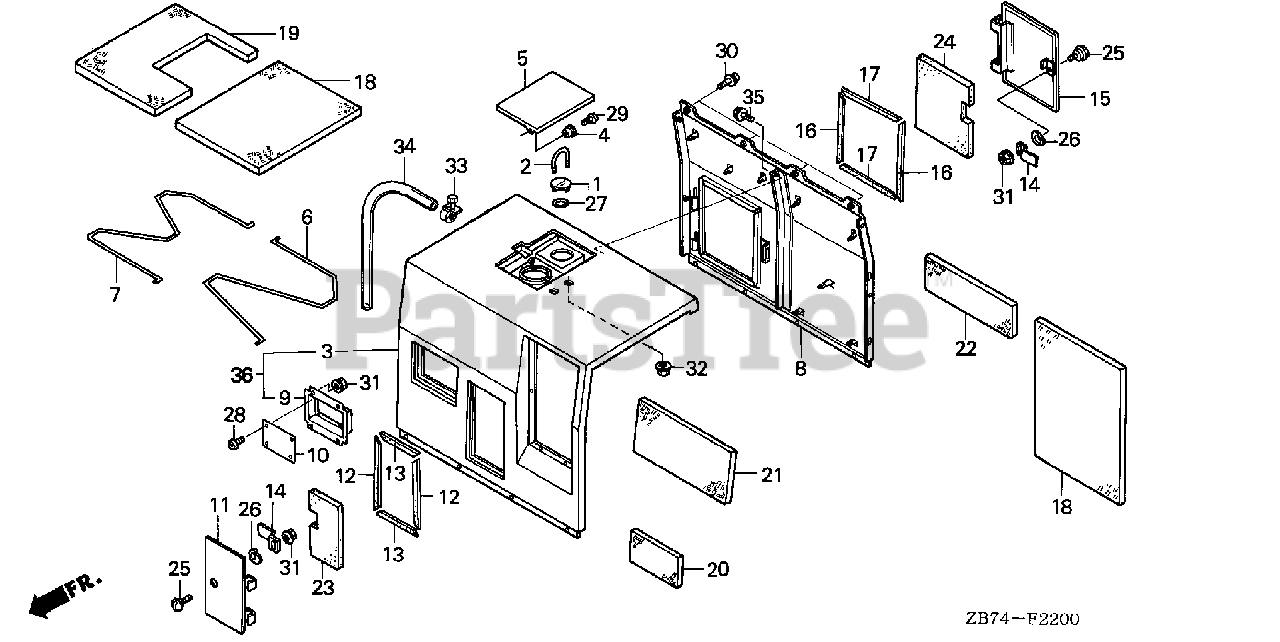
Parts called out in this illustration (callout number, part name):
1	CAP, FUEL METER
2	HOOK, HANGER
4	BUSH, FUEL CAP COVER
5	COVER, FUEL CAP *R280* (POWER RED)
6	WIRE, R. INSULATOR HOLDER
7	WIRE, L. INSULATOR HOLDER
8	PANEL, RR. *R280* (POWER RED)
10	PLATE, REMOTE CONTROL CASE
11	LID, FR. MAINTENANCE *R8* (BRIGHT RED)
12	SEAL A, MAINTENANCE LID
13	SEAL B, MAINTENANCE LID
14	PLATE, MAINTENANCE LID LOCK
15	LID, RR. MAINTENANCE *R280* (POWER RED)
16	SEAL, MAIN LID
17	SEAL, MAIN LID
18	INSULATOR A, MAINTENANCE LID COVER
19	INSULATOR B, MAINTENANCE LID COVER
20	INSULATOR C, MAINTENANCE LID COVER
21	INSULATOR E, MAINTENANCE LID COVER
22	INSULATOR, RR. PANEL (B)
23	INSULATOR, FR. MAINTENANCE LID
24	INSULATOR, RR. MAINTENANCE LID
25	BOLT, MAINTENANCE LID LOCK
26	WASHER, WAVE (12MM)
27	O-RING (56X2.4)
28	SCREW, PAN (5X10)
29	SCREW, HEADLIGHT SETTING
30	SCREW-WASHER (6X12)
31	NUT, FLANGE (6MM)
32	NUT, FLANGE (10MM)
33	CLIP, TUBE (A16)
34	BULK HOSE, VINYL (12X16X3000) (12X16X700)
35	BOLT, FLANGE (6X12)
36	COVER, MAIN *R280* (POWER RED)
